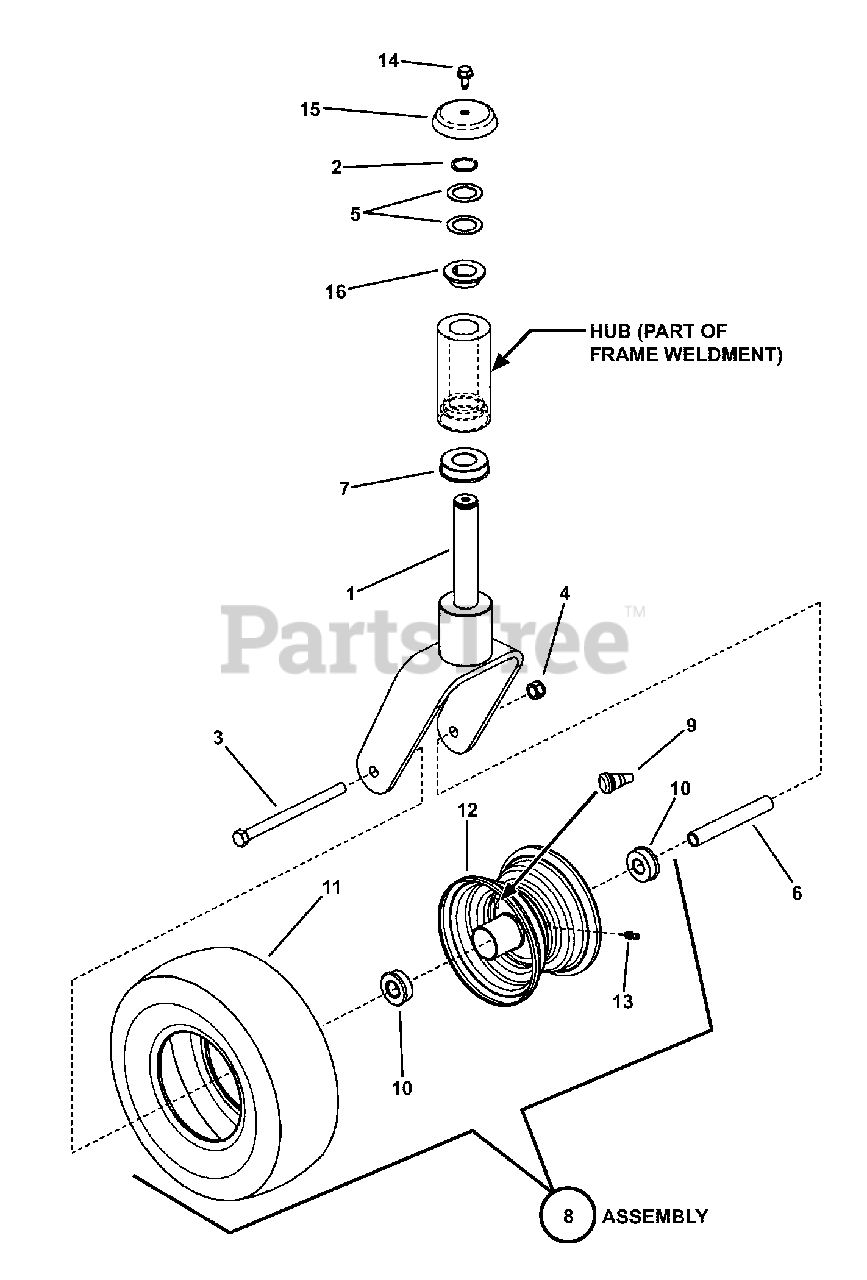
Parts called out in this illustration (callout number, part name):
1	WELDMENT, Caster (Black textured)
1	WELDMENT, Caster (Red)
2	RING, 1" External Retaining
3	SCREW, 7/16-14 x 6" Hex Head Cap, GR 5
4	NUT, 7/16-14 HEX NYLON LOCK
5	BUSHING, 1" Machine
6	TUBE, Caster Wheel (5/8" O.D. x 4.510)
7	BALL BEARING, Flanged, 1" I. D. x 2 x 5/8"
8	ASSY, Front Wheel & Tire (incl. items 9-13)
9	AIR VALVE STEM & CAP, Snap-In
10	BALL BEARING, .625 I.D. x 1.38
11	TIRE, 11 x 4.00-5, Smooth Tread
12	RIM, 5.00 Dia. x 3.00
13	FITTING, Lube (1/4-28 thread)
14	SCREW, 5/16-18 x 5/8" Hex Washer Self-Tap
15	CAP, Caster Shaft (Black)
15	CAP, Caster Shaft (Red)
16	BUSHING, Idler PM
